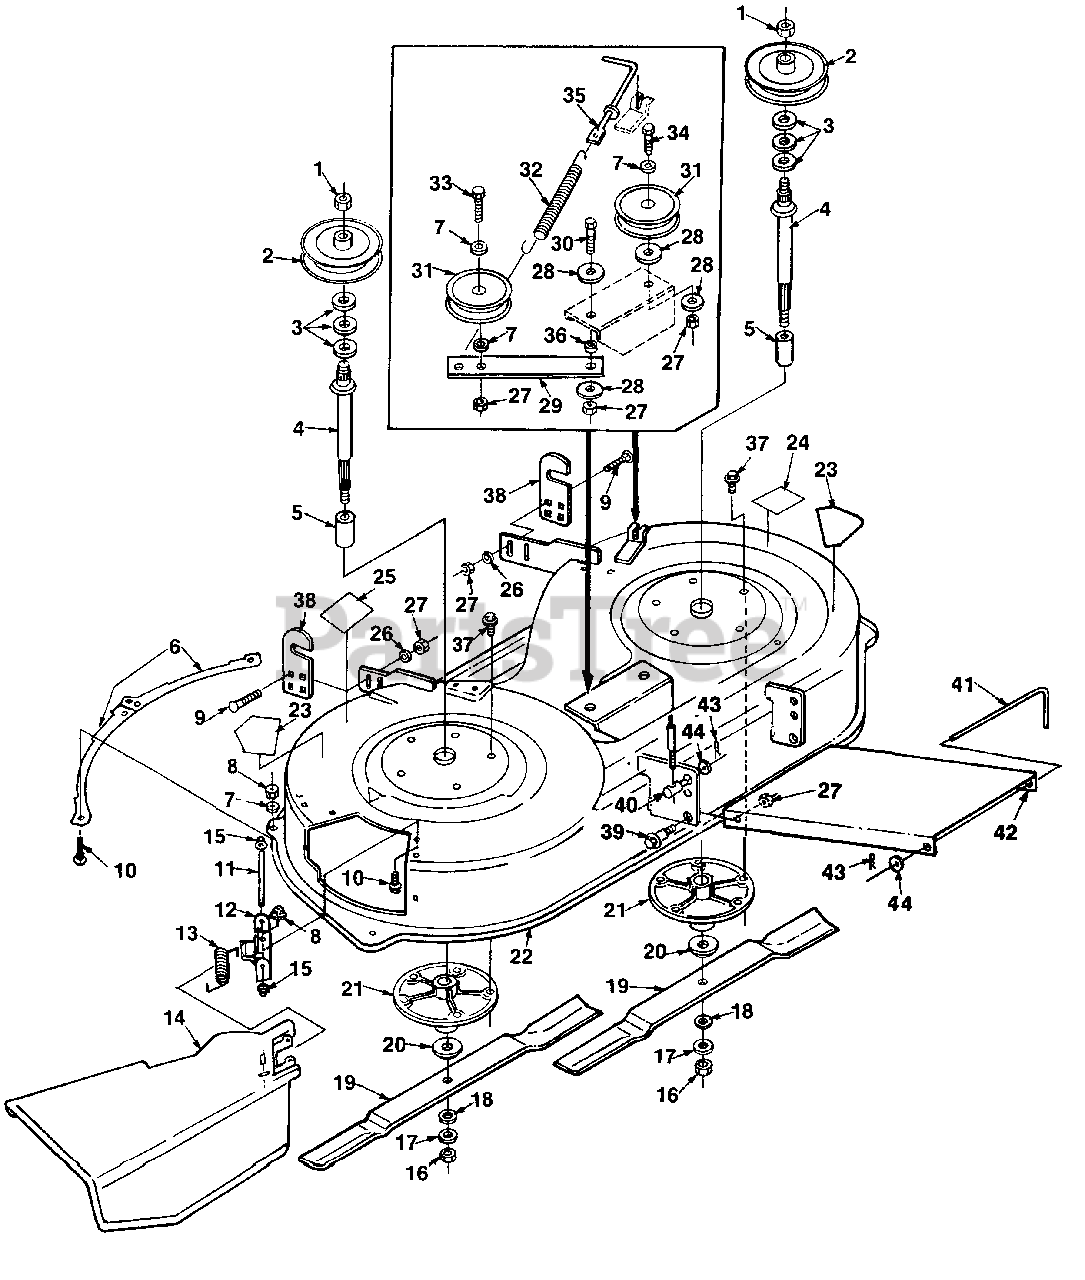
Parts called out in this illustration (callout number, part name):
1	NUT- Center lock (9/16-18)
2	PULLEY- Cutter head
3	WASHER- Flat
4	SPINDLE- Cutter head
5	SPACER- Spindle
6	PLATE- Air cut off
7	WASHER- Flat (3/8")
8	NUT- Flange (5/16-18)
9	BOLT- Rd. hd., sq. neck (3/8-16 x 1 1/4")
10	BOLT- Rd. hd., sq. neck
11	ROD- Deflector
12	BRACKET- Chute hinge
13	SPRING- Torsion
14	CHUTE- Deflector Assy.
15	NUT- Pal, push (3/8")
16	NUT- Hex (9/16-18)
17	WASHER- Flat
18	WASHER- Belleville
20	BLADE- Adaptor
21	HOUSING- Spindle
22	DECK ASSEMBLY
23	DECAL- Danger
24	DECAL- No step
25	DECAL- Belt installation
26	WASHER- Flat
27	NUT- Hex lock (3/8-16)
28	WASHER- Blade mtg.
29	ARM- Idler
30	SCREW- Hex hd., cap (3/8-16 x 1 1/2")
31	PULLEY- Idler
32	SPRING- Extension
33	SCREW- Hex hd., cap (3/8-16 x 1 3/4")
34	SCREW- Hex hd., cap (3/8-16 x 2")
35	ROD- Spring release
36	SPACER- Idler arm
37	SCREW- Hex washer hd.
38	BRACKET- Rear hanger
39	BOLT- Shoulder
40	PIN- Clevis
41	PIN- Link
42	BRACKET- Link
43	PIN- Hair cotter
44	WASHER- Flat
